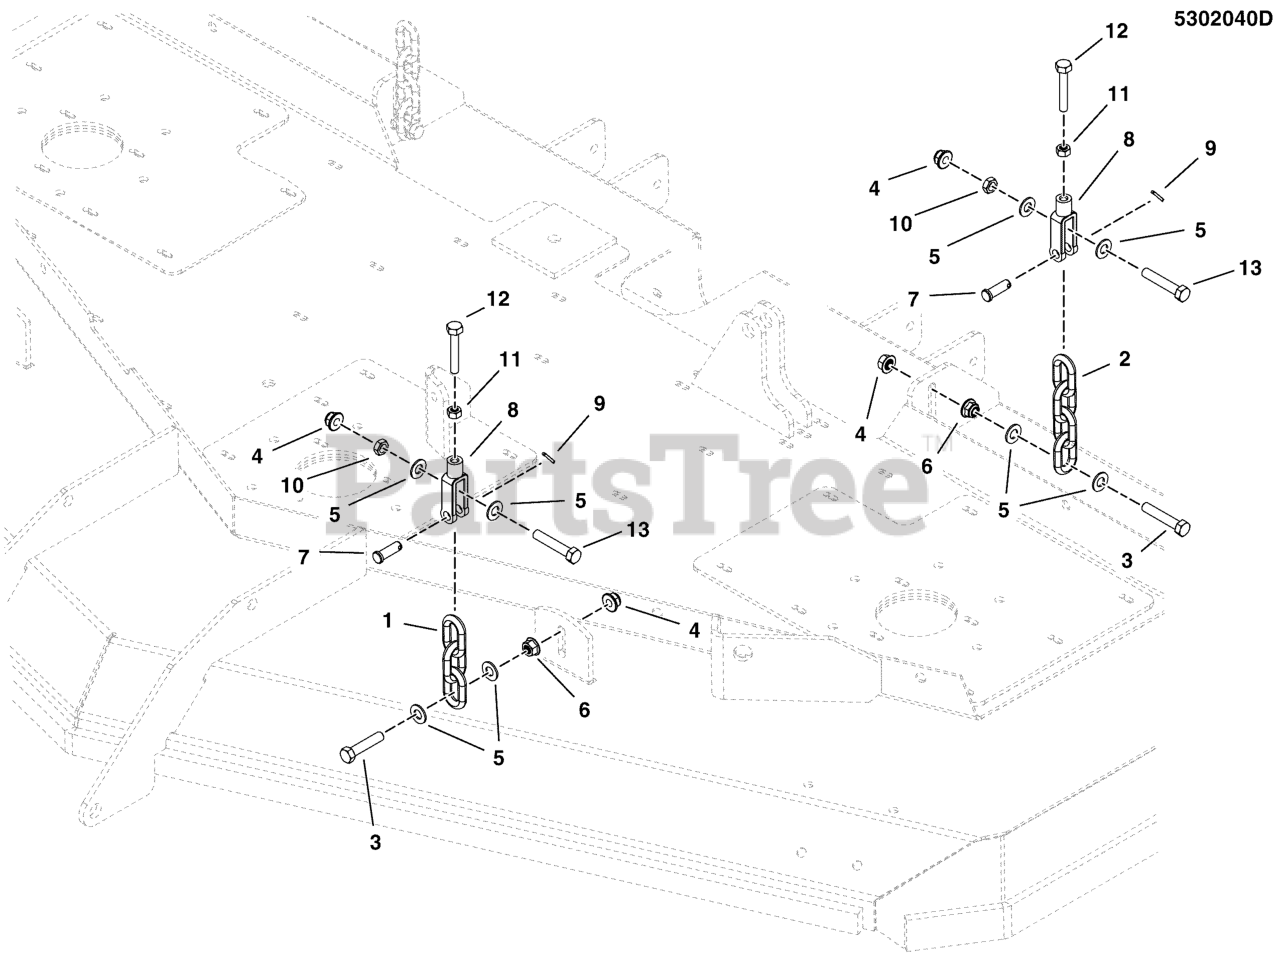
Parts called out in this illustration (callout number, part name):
1	CHAIN, 5/16 GD30, 3 LINKS
2	CHAIN, 5/16" GD30, 4 LINKS
3	BOLT, 3/8-16 X 1-3/4" GD5 CZ
4	NUT, 3/8-16 HEX NYLOCK FLANGE
5	WASHER, 3/8 SAE
6	NUT, 3/8-16 HEX SERRATED FLANGE
7	PIN, CLEVIS, 3/8 X 1-1/8, CZ
8	CLEVIS, 5/16-18, 3/8 PIN HOLE, CLR ZINC
9	PIN, 3/32 X 0.750, COT, ZINC/CLEAR
10	NUT, 3/8-16 HEX JAM
11	NUT, 5/16-18 HEX
12	BOLT, 5/16-18 X 2 GD5 TFL
13	BOLT, 3/8-16 X 2, GD5, CZ
